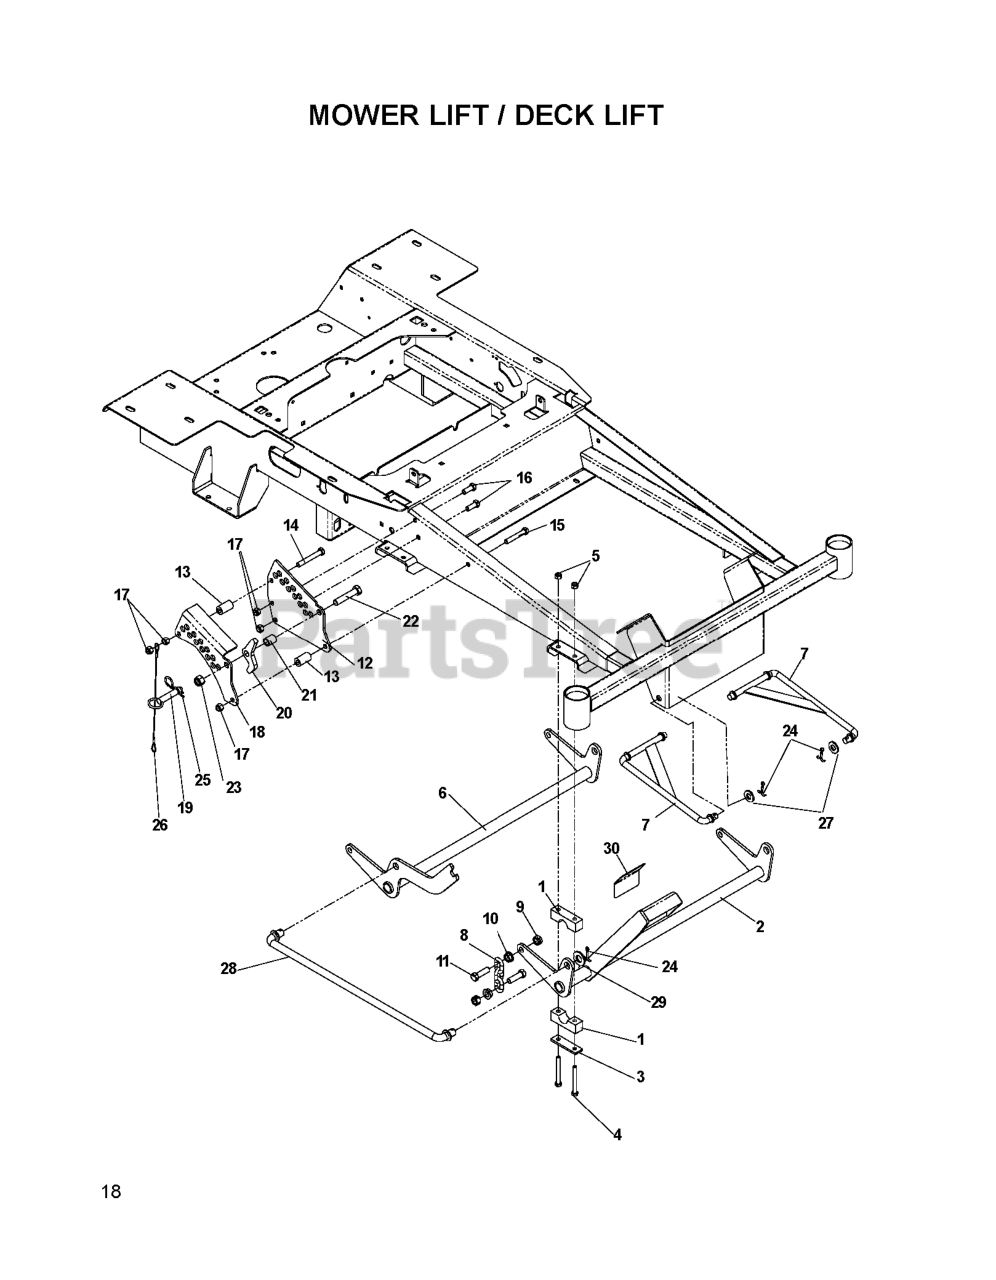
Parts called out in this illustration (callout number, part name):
1	PILLOW BLOCK
2	FRONT LIFT SHAFT
3	REINFORCEMENT BAR
4	HCS 5/16C X 2-3/4
5	NUT 5/16 NYLOC
6	LIFT SHAFT, REAR
7	STRUT LINKAGE
8	LIFT CHAIN - 3 LINK
9	NUT 7/16C CENTERLOCK
10	NUT 7/16C WHIZ
11	HCS 7/16C X 1 1/2
12	HEIGHT ADUST PLATE
13	DECK LIFT SPACER
14	SCREW 3/8C X 2 3/4 HEX CAP
15	HCS 3/8C X 2 1/4
16	HCS 3/8-16X1.GRD.5.ZD
17	NUT 3/8-16 NYLOC
18	HEIGHT ADJUST PLATE, OUTER
20	PAWL, STOP
22	HEX SCREW 1/2-13 X 2.5" GR 5
23	NUT 1/2-13 HEX NYLOC ZD
24	COTTER PIN
25	HAIRPIN #4
27	WASHER 1/2" FLAT
28	CROSS LINK
29	WASHER 5/8 FLAT
30	ANTI-SKID PAD
